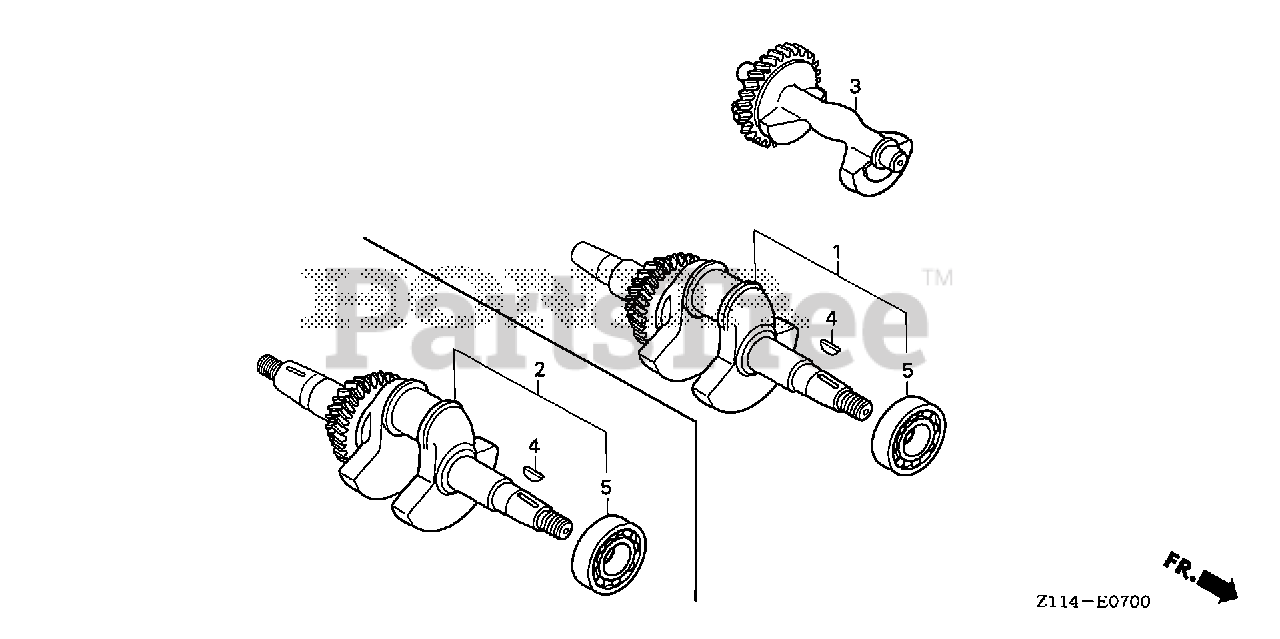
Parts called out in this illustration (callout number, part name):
1	CRANKSHAFT
3	WEIGHT, BALANCER
4	KEY, SPECIAL WOODRUFF (25X18)
5	BEARING, RADIAL BALL (6207SH)
